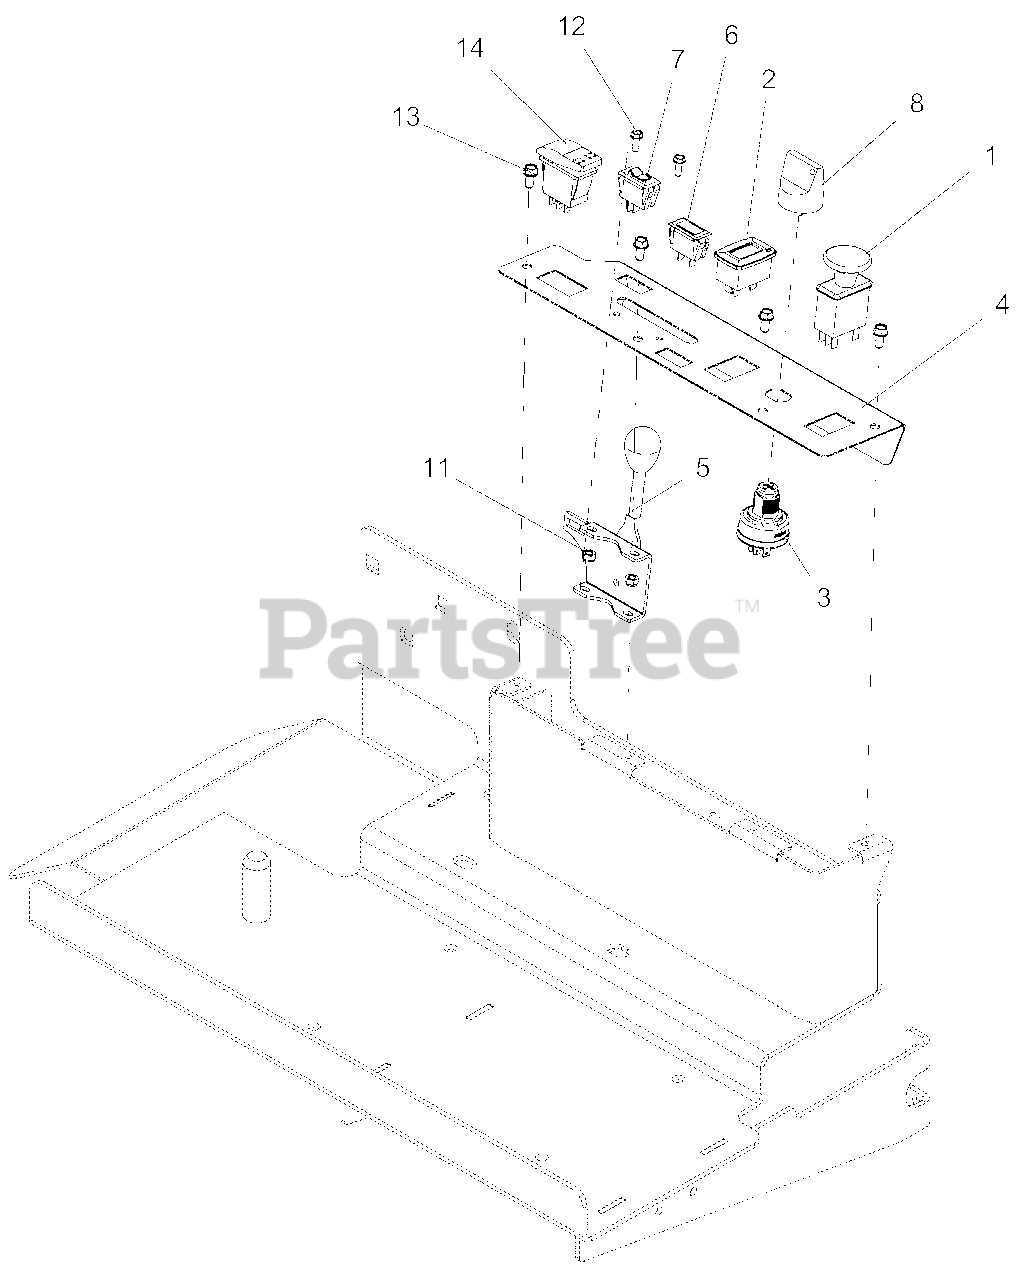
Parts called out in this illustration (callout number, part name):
1	SWITCH, CLUTCH
2	METER, HOUR W/MAINTENANCE
3	SWITCH, IGNITION
4	PANEL, CONTROL PT400 - LP
5	CABLE, THROTTLE
6	LIGHT, INDICATOR
7	SWITCH, ROCKER SPST REV
8	KEY, W/ COVER
11	NUT-LK-NYL #10-24 YWZC
12	SCR-MCH 10-24X.50 HWH YWZC
13	SCR-TAP .25-20X.50 HWH TR YWZ
14	SWITCH, DBL POLE DBL THROW
